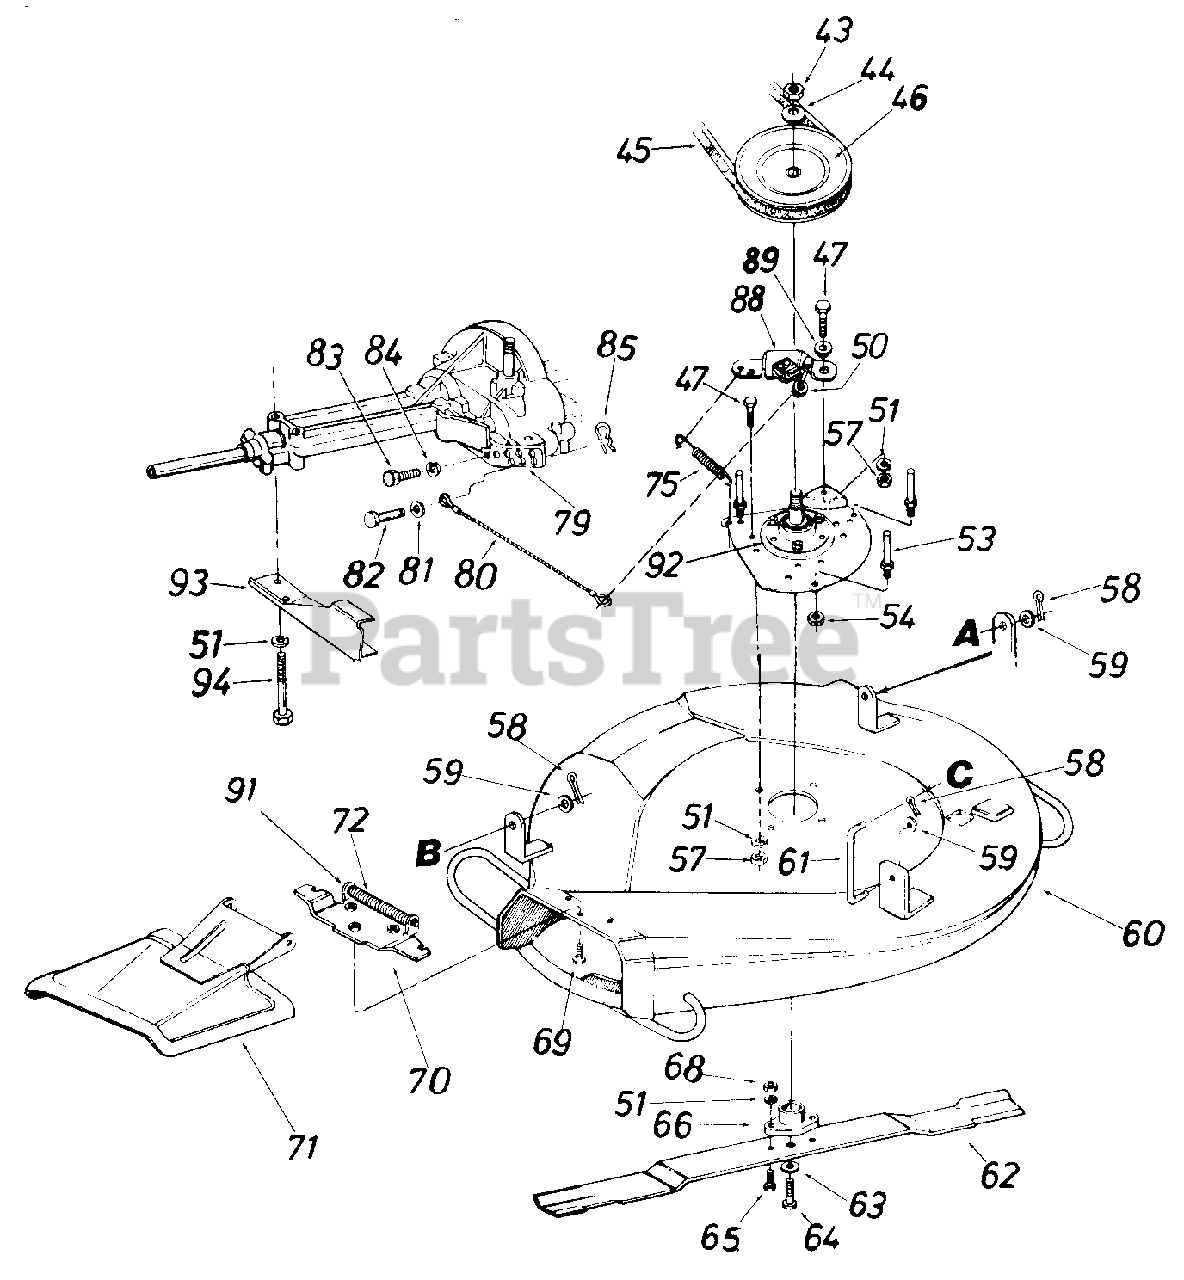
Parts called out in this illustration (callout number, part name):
43	Hex Jam Nut 5/8-18 Thd.
44	Bell-Wash. .63" I.D. x 1.25n O.D.
45	V-Belt 1/2 x 52" Lg.
46	1/2" V-Pulley .625" I.D. x 6.0" O.D.
47	Hex Bolt 5/16-18 x .75"
50	Cap Speed Nut 1/4" Rod
51	L-Wash. 5/16" I.D.*
53	Stud 3/8-16 x 3.00' Lg.
54	Hex Jam Nut 3/8-16 Thd.
57	Hex Nut 5/16-18 Thd.
58	Intern. Cotter Pin 1/2" Dia.
59	Fl-Wash. .385" I.D. x .87"
60	26" Deck Ass'y.
61	Deck Link 3.9" Lg.
62	26" High Lift Blade
63	Bell-Wash. .39" I.D. x 1.38"
64	Hex Bolt 3/8-24 x 1.0"
65	Hex Bolt Spec. 5/16-24 x 1.0" Lg.
66	Blade Adapter
68	Hex Nut 5/16-24 Thd.
69	Hex Wash. S-Tap Scr. 1/4-20 x.50" Lg.
70	Adapter Plate-Chute
71	Chute Cover Ass'y. Comp.
72	Torsion Spring
75	Extension Spring 3.25" Lg.
79	Lower Inside Belt Guard
80	Brake Cable 11.75" Lg.
81	Fl-Wash. .281" I.D. x .50"
82	Clevis Pin 1/4" Dia. x .53" O.D.
83	Hex Bolt 1/4-20 x .62n Lg.
84	L-Wash. 1/4" I.D.
85	Intern. Cot.-Pin 5/16" Dia.
88	Blade Brake Brkt. Ass'y.
89	Shld. Spacer 27n Lg.
91	Hinge Pin
92	Blade Spindle Ass'y. Comp.
93	Lower Outside Belt Guard
94	Hex Bolt 5/16-18 x 2.5" L.
